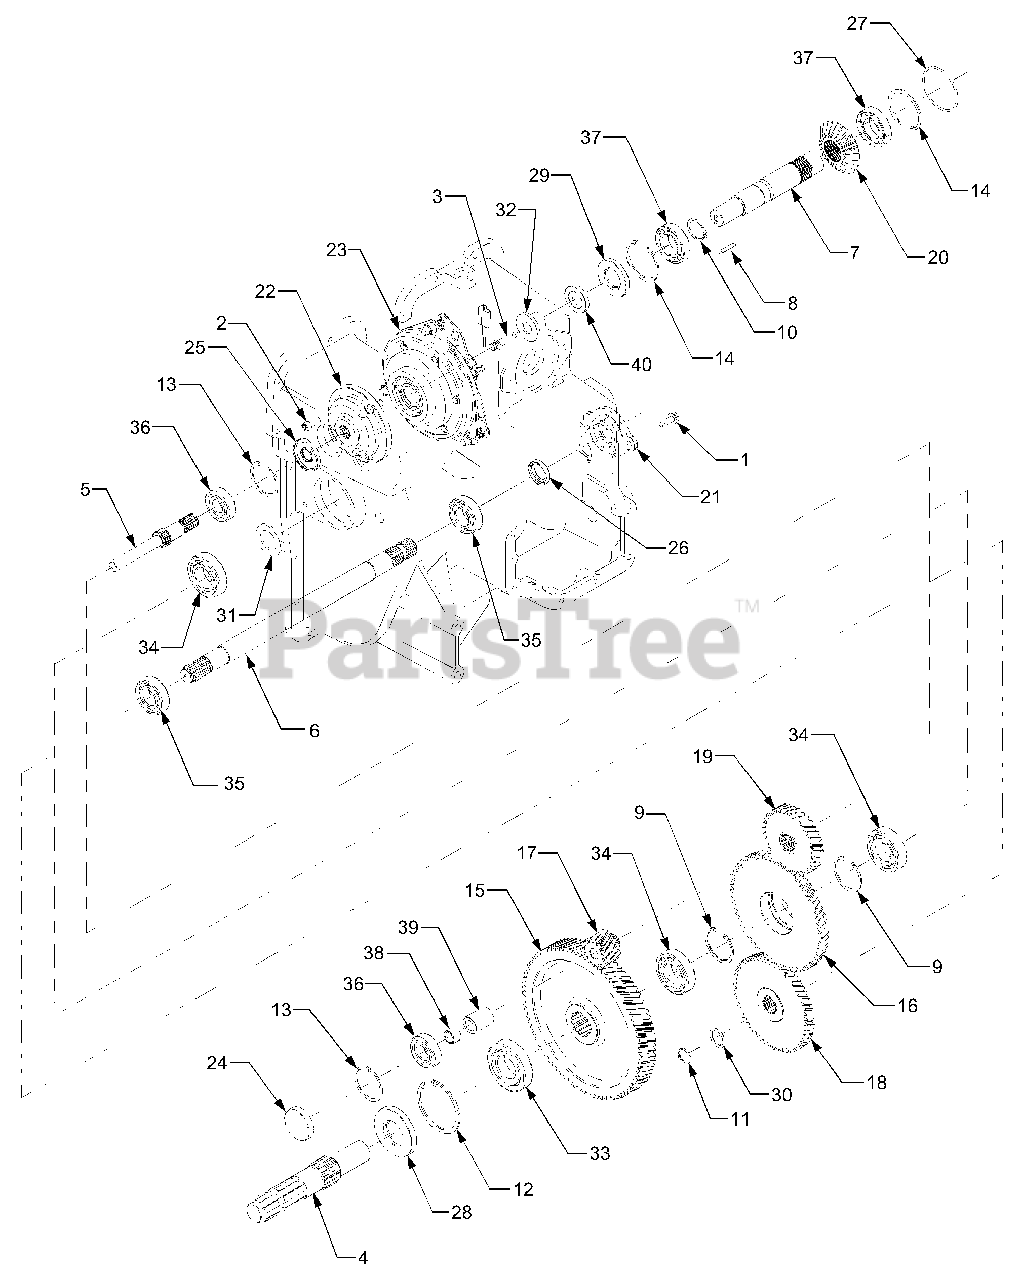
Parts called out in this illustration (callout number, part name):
1	Screw, Hex Wash. Hd. Tapp. 5/16-18 x .875
2	Screw, Socket Hd 5/16-18 x .75
3	Screw, 12 Pt. Wash. Hd. w/Patch 3/8-16 x 1.25
4	Shaft, 540 PTO
5	Shaft, Clutch Back
6	Shaft, 2000 PTO
7	Shaft, Input PTO
8	Key, Square, 1/4 x 1. 0
9	Ring, Retaining
10	Ring, Retaining
11	Ring, Retaining
12	Ring, Retaining
13	Ring, Retaining
14	Ring, Retaining
15	Gear, 540 PTO, 81T
16	Gear, 2000 PTO , 61T
17	Gear, Pinion, 540 PTO:14T
18	Gear, Pinion, 2000 PTO:54T
19	Gear, Pinion, 2000 PTO:34T
20	Gear, Bevel, 32T
21	Cover, 2000 PTO
22	Adapter, PTO Output
23	Clutch Assy. PTO
24	Plug, Oil, 1.875 x .375
25	Seal, Oil
26	Seal, Oil
27	O-Ring, 2.425 ID x .103
28	Seal, Oil
29	Seal, Oil
30	Washer, Flat, .865 x 1.145 x .030
31	Washer, Thrust
32	Spacer, Shoulder
33	Bearing, Ball
34	Bearing, Ball
35	Bearing, Ball
36	Bearing, Ball
37	Bearing, Ball
38	Spacer, 15mm x 20mm x 14mm
39	Spacer, .6 x 1.0 x 1.345
40	Spacer, 1.004 x 1.375 x .25
